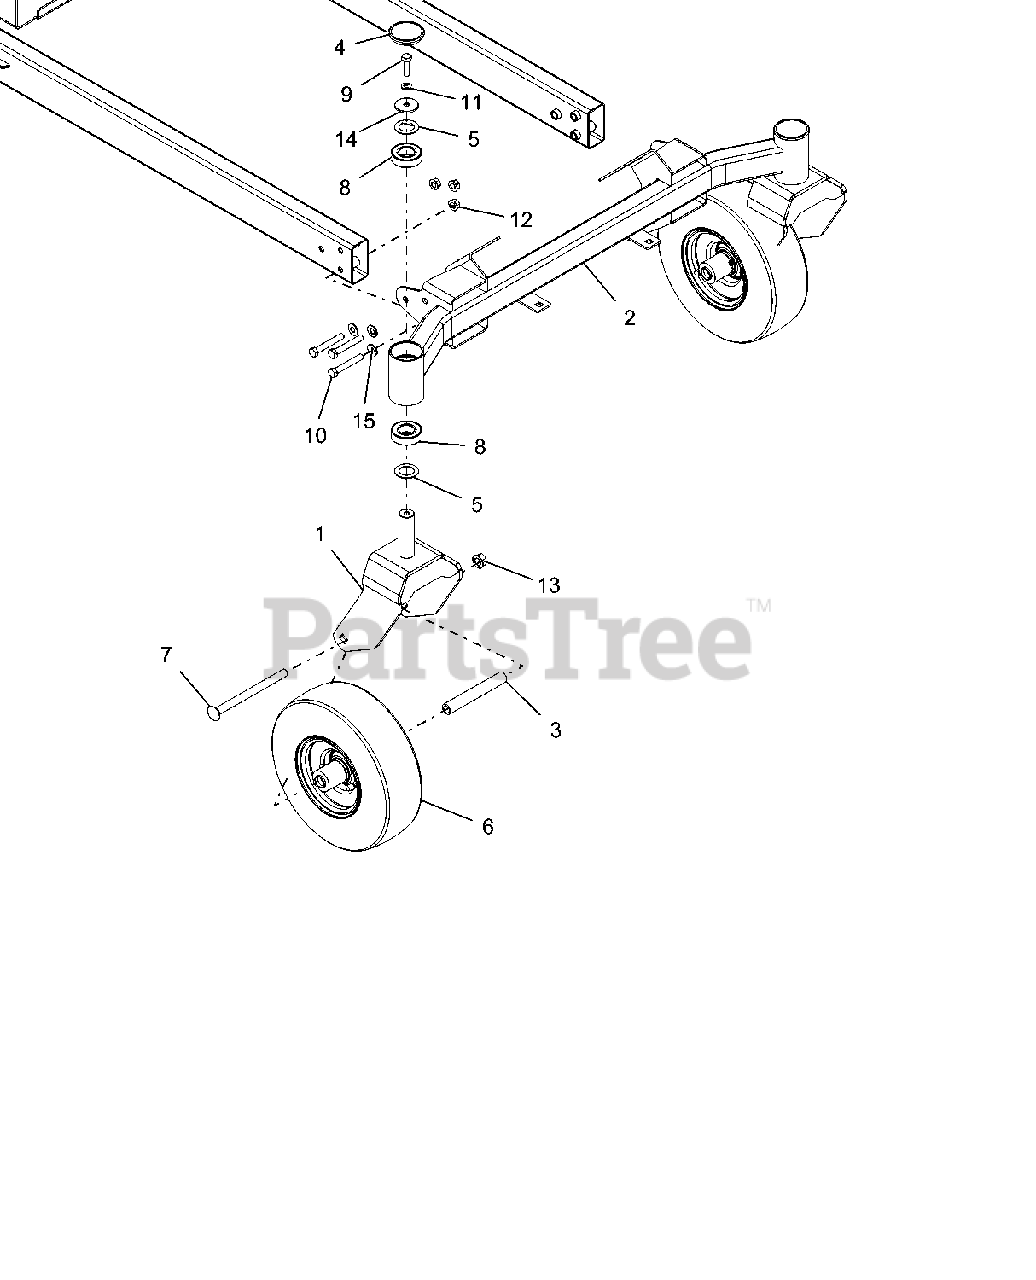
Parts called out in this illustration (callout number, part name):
1	WMT, CASTER FORK
2	WLDMT, AXLE FRONT
3	SPACER, ROLLED WHEEL
4	CAP, DUST
5	WSHR-HRD-THRS 1.007X1.542X.062
6	ASM, WHL/TIRE 11X4.00-5
7	BLT-RDHDSQNK .50-13X6.50 GR5 Y
8	BRG,BALL 1.00X2.00X.563(1641)
9	@BLT-HEX .38-16X1.25 GR5 YWZC
10	BLT-HEX .38-16X2.50 GR8 YWZC
11	@WSHR-LK .38X.094 REG YWZC
12	NUT-LK-TOP-FLG .38-16 GRG YWZC
13	@NUT-LK-TOP-FLG .50-13 YWZC
14	WSHR-FL-STL .380X1.50X.125YWZC
15	WSHR-HDND .406X.812X.055
